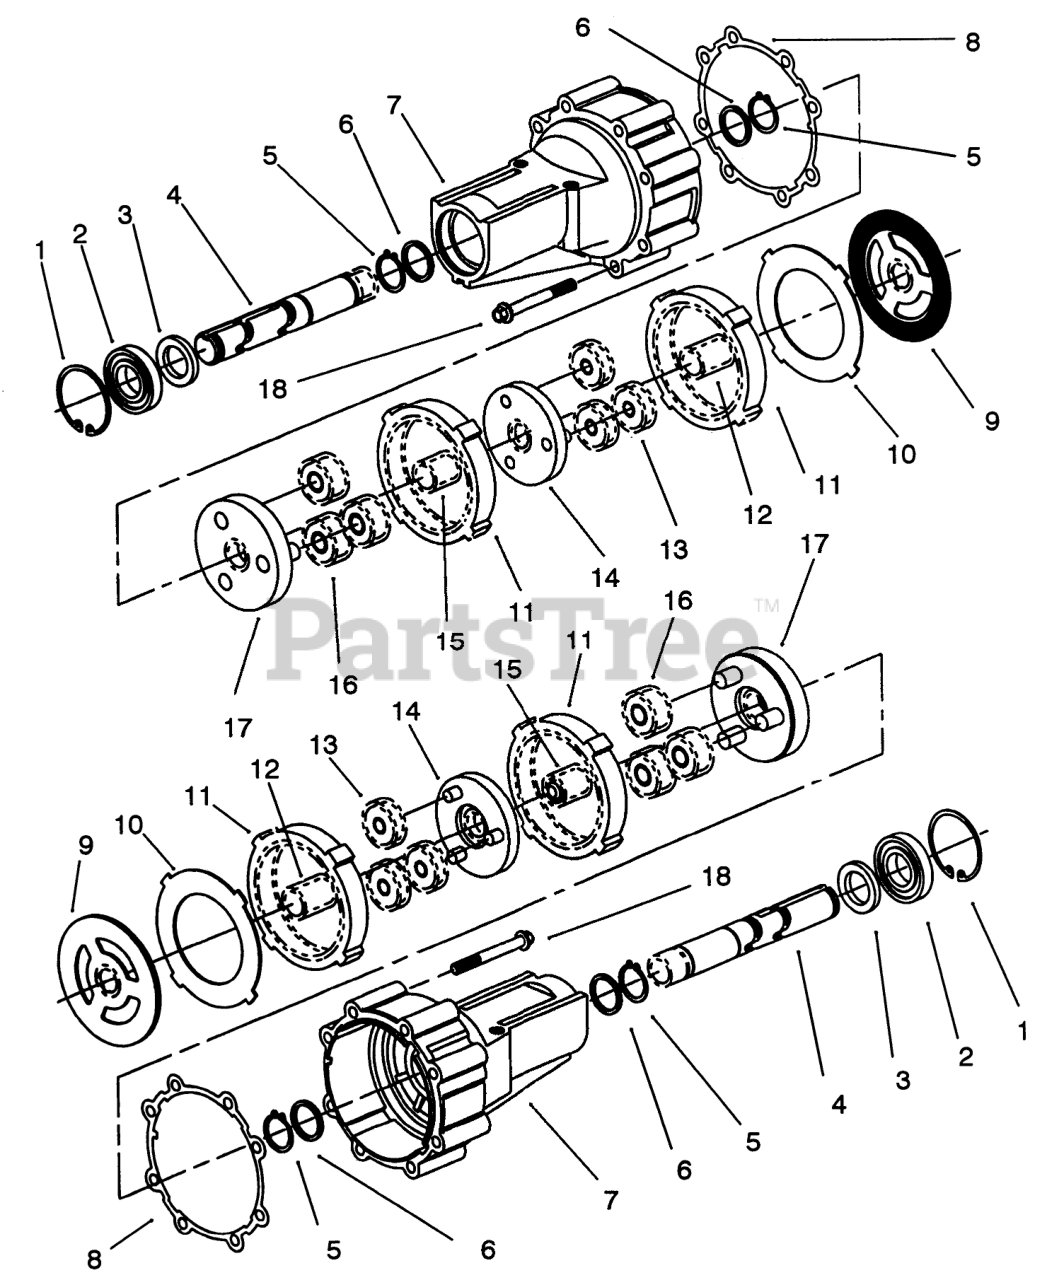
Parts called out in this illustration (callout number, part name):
1	RETAINING RING
2	BALL BEARING
3	RADIAL LIP SEAL
4	AXLE SHAFT
5	RETAINING RING
6	THRUST WASHER
7	AXLE HOUSING
8	AXLE HOUSING GASKET
9	REACTION PLATE
10	BACKUP PLATE
11	54 TOOTH RING GEAR
12	15 TOOTH FIRST GEAR
13	PLANET FIRST GEAR
14	PRIMARY CARRIER
15	SECOND GEAR
16	SECOND GEAR
17	SECONDARY CARRIER
18	5/16 HEX HEAD SCREW
